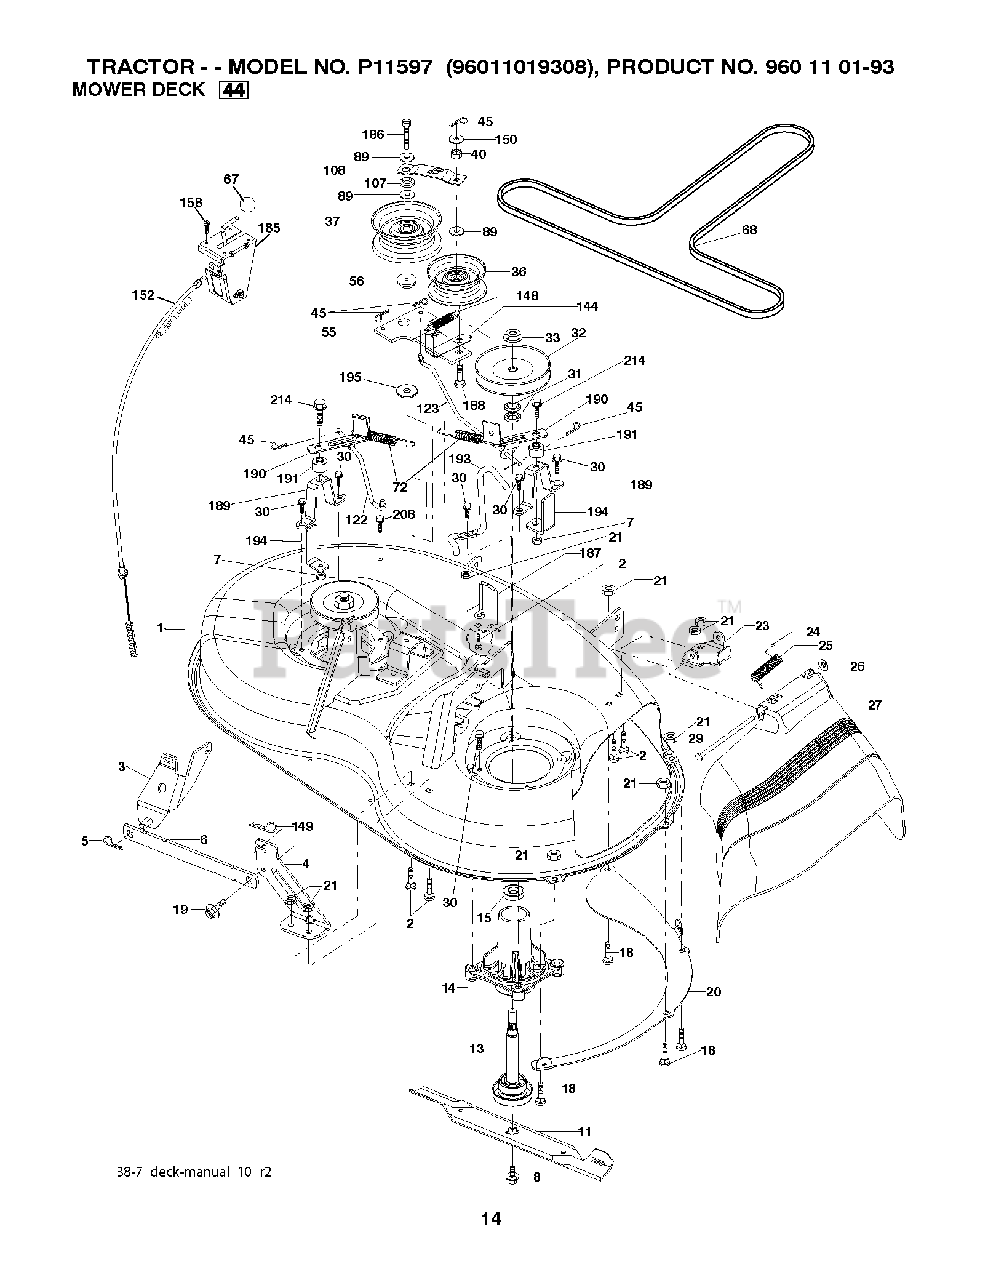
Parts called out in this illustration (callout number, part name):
1	DECK.WELDMENT.38"2005
2	BOLT
3	BRKT ASM SWAY BAR
4	BRACKET DECK SWAY BAR 38"/42"
5	RETAINER-SPRNG RB
6	BAR SWAY DECK
7	NUT.71038.31-18.HEX.NYLOCK
8	BOLT.WASHER.ASM.7/16-2
11	BLADE 38" PREMIUM
13	SHAFT.ASM.MDRL.N/GREASE.38
14	HOUSING MANDREL
18	BOLT
19	BOLT SHD 5/16-18
20	BAFFLE VORTEX
21	LOCKNUT
23	BRKT.DEFLECTOR.38"2005+
24	CAP-SLEEVE LT
25	SPRING.TORSION.DEFLECT
27	Deflector Shield, 38-7/97cm
29	ROD.HINGE
30	SCREW, WASHER HEAD
31	WASHER.SPACER.MANDREL
32	PULLEY MANDREL
33	NUT.FLANGE.LOCK.TOP
36	FLAT IDLER PULLEY
37	PULLEY.IDLER.FLAT.UNPLATED
40	LOCKNUT
45	RETAINER M
56	SPACER.RETAINER.MOWER
67	KNOB T (3/8 HOLE)
68	V-BELT.MOWER.38"2005+
72	SPRING.BRAKE.RETURN.38"
89	WASHER
107	SPACER.IDLER.ARM
108	STIFFENER.IDLER.ARM
122	ROD, BRAKE LH LINK
123	LINK.BRAKE.38"RIGHT
148	IDLER RETURN SPRING
149	SPRING.RETAINER.YELLOW.ZINC
150	WASHER LT
152	CABLE.CLUTCH.38".SERVICE
158	SCREW
185	HEAD ASM. CABLE CLUTCH
186	SCREW.HXWSH.3/8
188	BOLT, CARRIAGE IDLER
189	STAND, BRAKE
190	ARM, BRAKE
191	SPACER, BRAKE
193	KEEPER BELT RH MANDREL
194	GUARD BRAKE
195	WASHER 12/32X2X10GA
208	SCREW 3/8-16X1/2
214	BOLT/WASHER ASM 5/16-18
